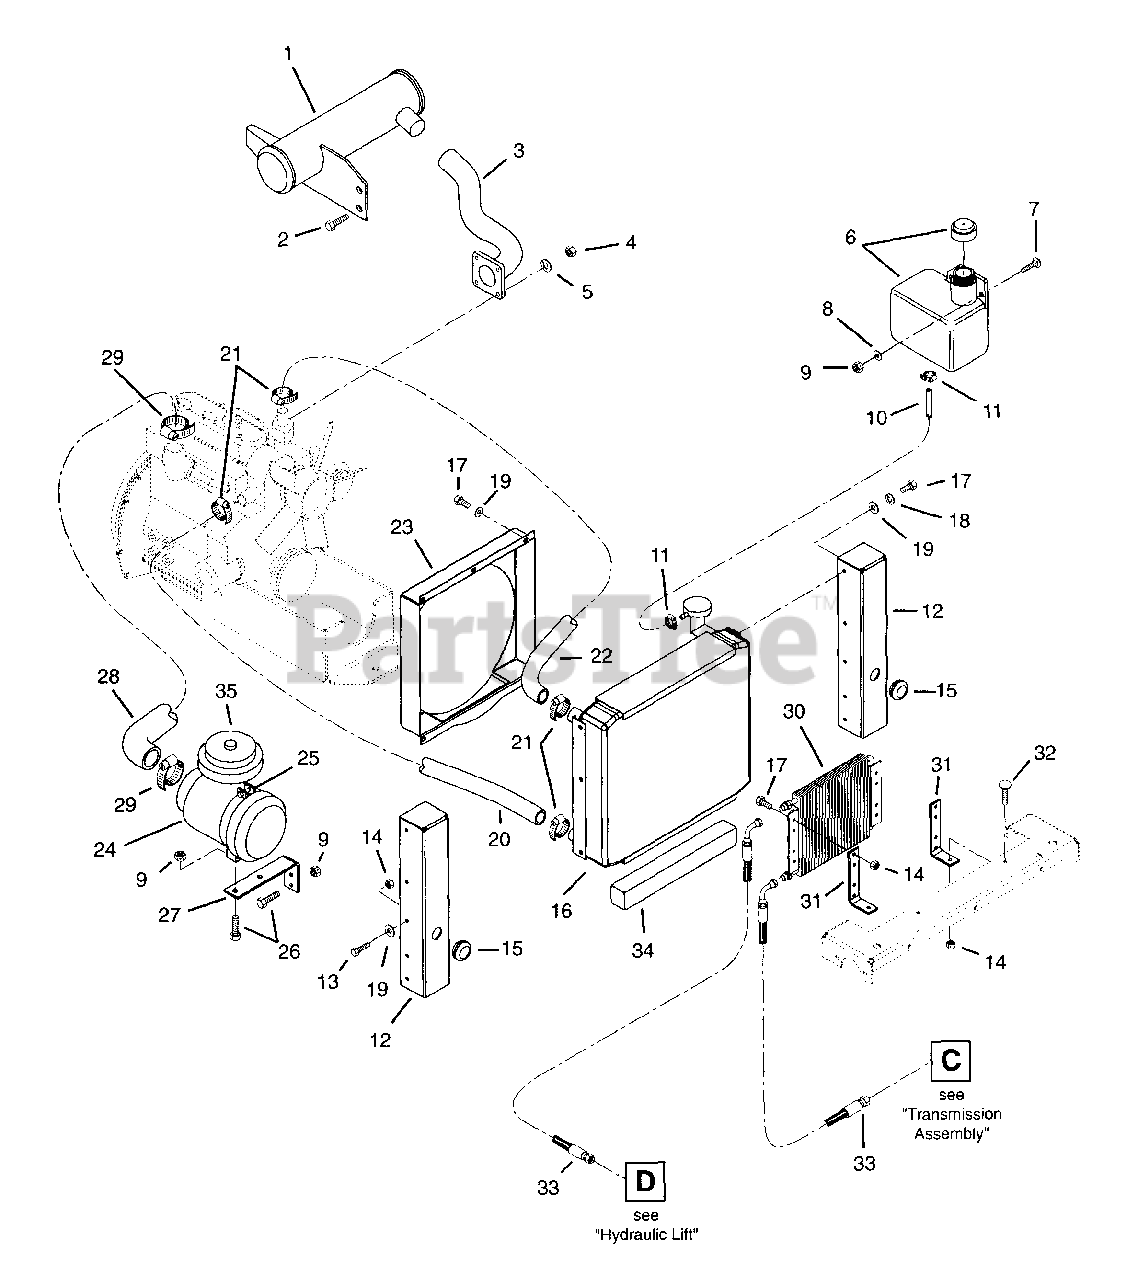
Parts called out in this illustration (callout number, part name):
2	Bolt-Hex M8 x 1.25 x 25 Grade 5
3	Manifold, Exhaust
4	Nut-Hex M8-1.25
5	Washer-Locking .31 x .078
6	Tank, Plastic 1.5 Quart
7	Bolt-Round Head Square Neck .31-18 x .75 Grade 5
8	Washer-Flat-Steel .312 x .734 x .065
9	Nut-Locking-Center .31-18
10	Gas Line-Bulk 1/4" I.D.
11	Hose Clamp
12	Mount, Radiator
13	Bolt-Hex .25-20 x .75 Grade 5
14	Nut-Locking-Center .25-20
16	Radiator
17	Bolt-Hex .25-20 x .50 Grade 5
18	Washer-Locking .25 x .062
19	Washer-Flat-Steel .281 x .62 x .065
20	Hose, Lower Radiator
21	Clamp, Hose 1.50 x .81 x 1.42
22	Hose, Upper Radiator
23	Weldment, Fan Shroud
24	Air Cleaner
24	Element, Air Cleaner
25	Bracket, Air Cleaner
26	Bolt-Hex .31-18 x .75
27	Bracket, Air Filter Mount
28	Hose, Air Cleaner
29	Clamp, 2.25 Dia. Hose
30	Cooler, Oil
31	Bracket, Oil Cooler Mount
32	Bolt-Round Head Square Neck .25-20 x .75 Grade 5
33	Assembly, Hydraulic Hose
34	Tape-Adhesive Backed Foam
35	Cap, Air Cleaner
